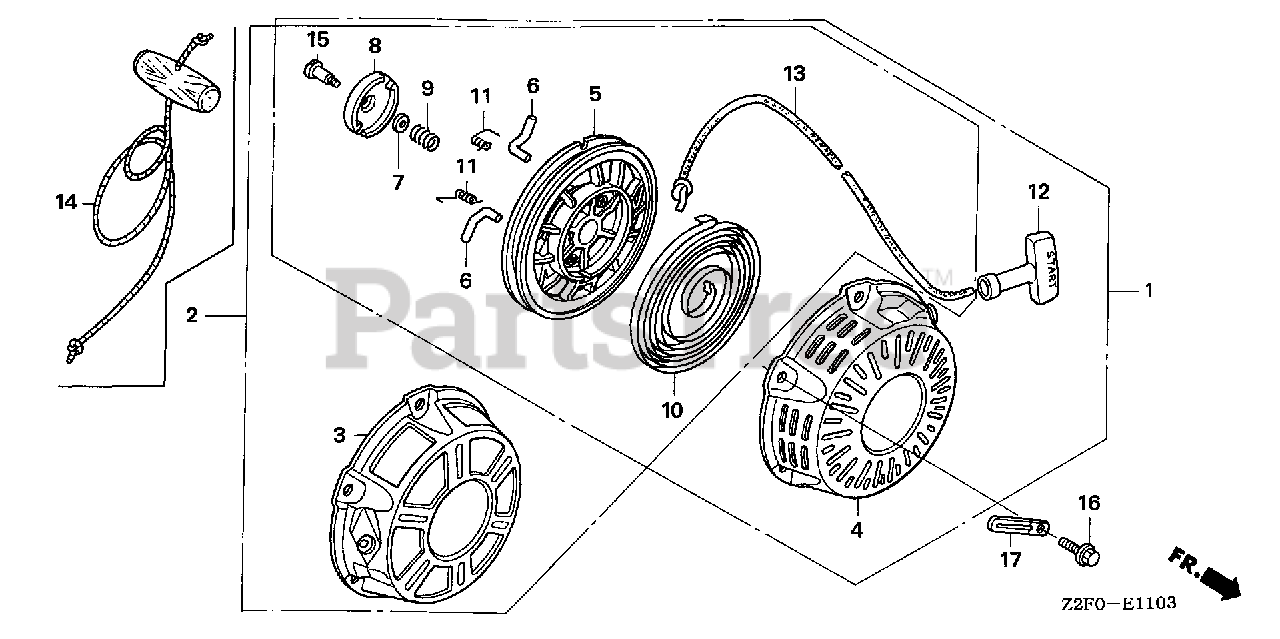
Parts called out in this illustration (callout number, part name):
1	STARTER ASSY., RECOIL *R280* (POWER RED)
4	CASE, RECOIL STARTER *R280* (POWER RED)
5	REEL, RECOIL STARTER (BLACK)
6	RATCHET, STARTER
7	PLATE, FRICTION
8	GUIDE, RATCHET
9	SPRING, FRICTION
10	SPRING, RECOIL STARTER
11	SPRING, RETURN
12	GRIP, STARTER
12	KNOB, RECOIL SRARTER
13	ROPE, RECOIL STARTER
15	SCREW, SETTING
16	BOLT, FLANGE (6X10)
